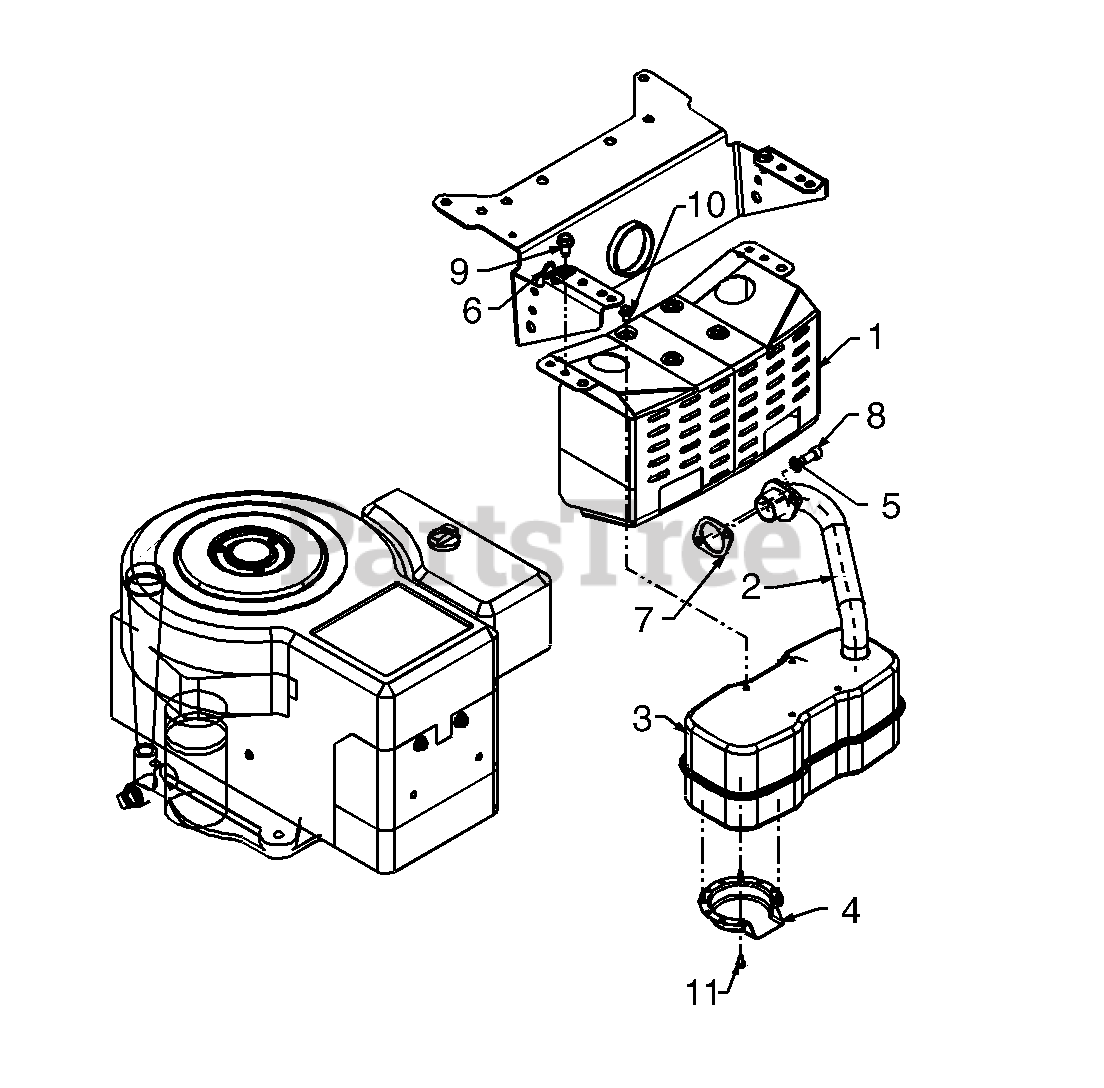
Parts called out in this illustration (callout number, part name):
2	Exhaust Pipe
3	Muffler
4	Muffler Deflector
5	L-Wash. 5/16" I.D.
6	Clamp
7	Exhaust Gasket
8	Socket Hd. Bolt 5/16-18 x .62" Lg.
9	Hex Wash Hd. TT-Tap Scr. 5/16-18 x .62" Lg.
10	Hex Wash. TT-Tap Scr. 1/4-20 x .5" Lg.
11	Hex Slot Scr. #8-32 x .38" Lg.
